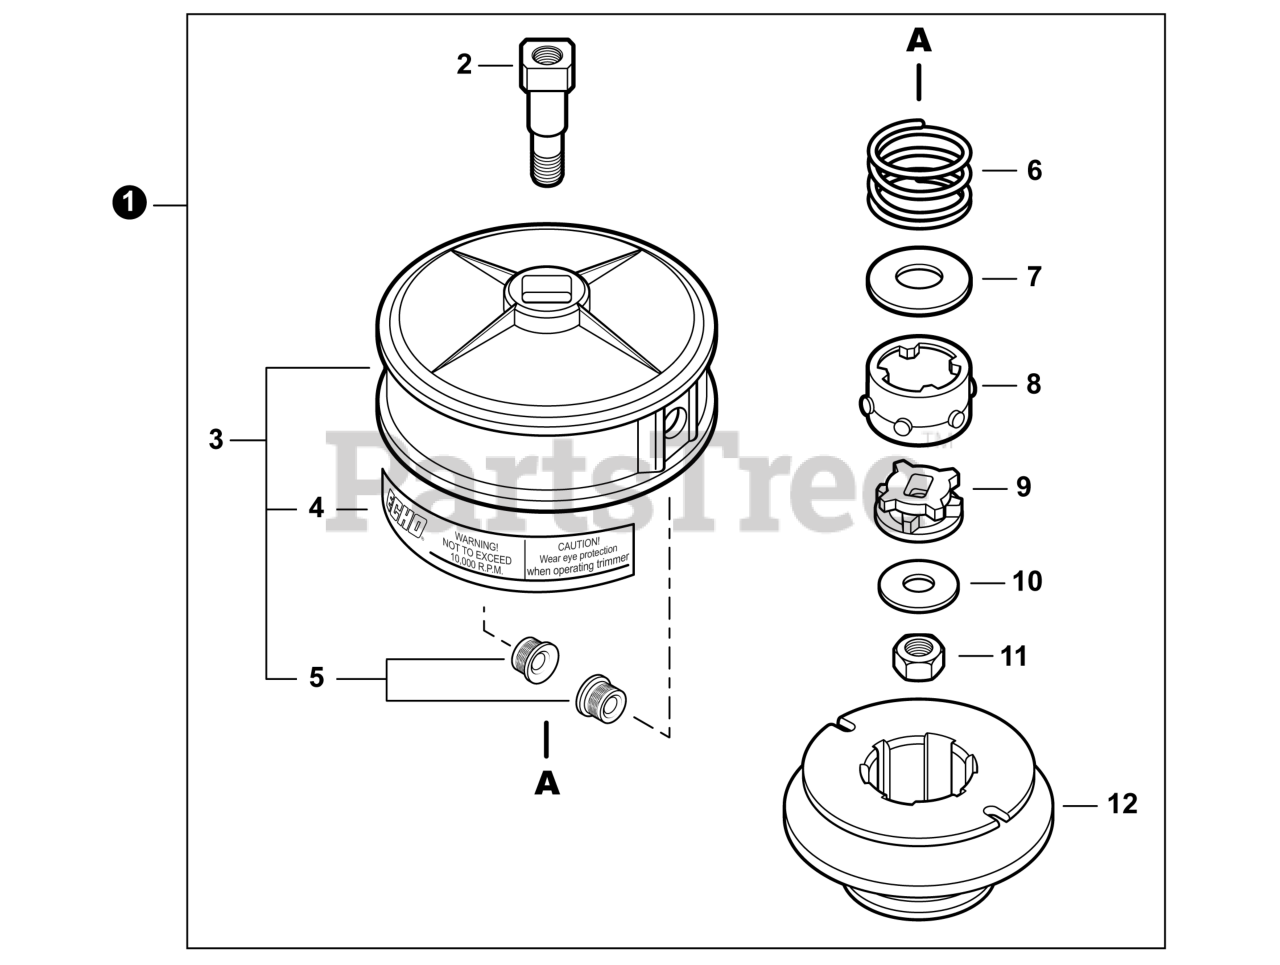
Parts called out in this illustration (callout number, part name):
1	TRIMMER HEAD, SRM ECHOMATIC®
2	STUD, ARBOR M10x1.25 FLH / 5/16"-24 MRH
3	HOUSING ASSY, SPOOL
4	LABEL - CAUTION
6	SPRING, COMPRESSION
7	WASHER 14
8	CAM, OUTER
9	CAM, INNER
10	WASHER 8
11	NUT, LOCK 8
